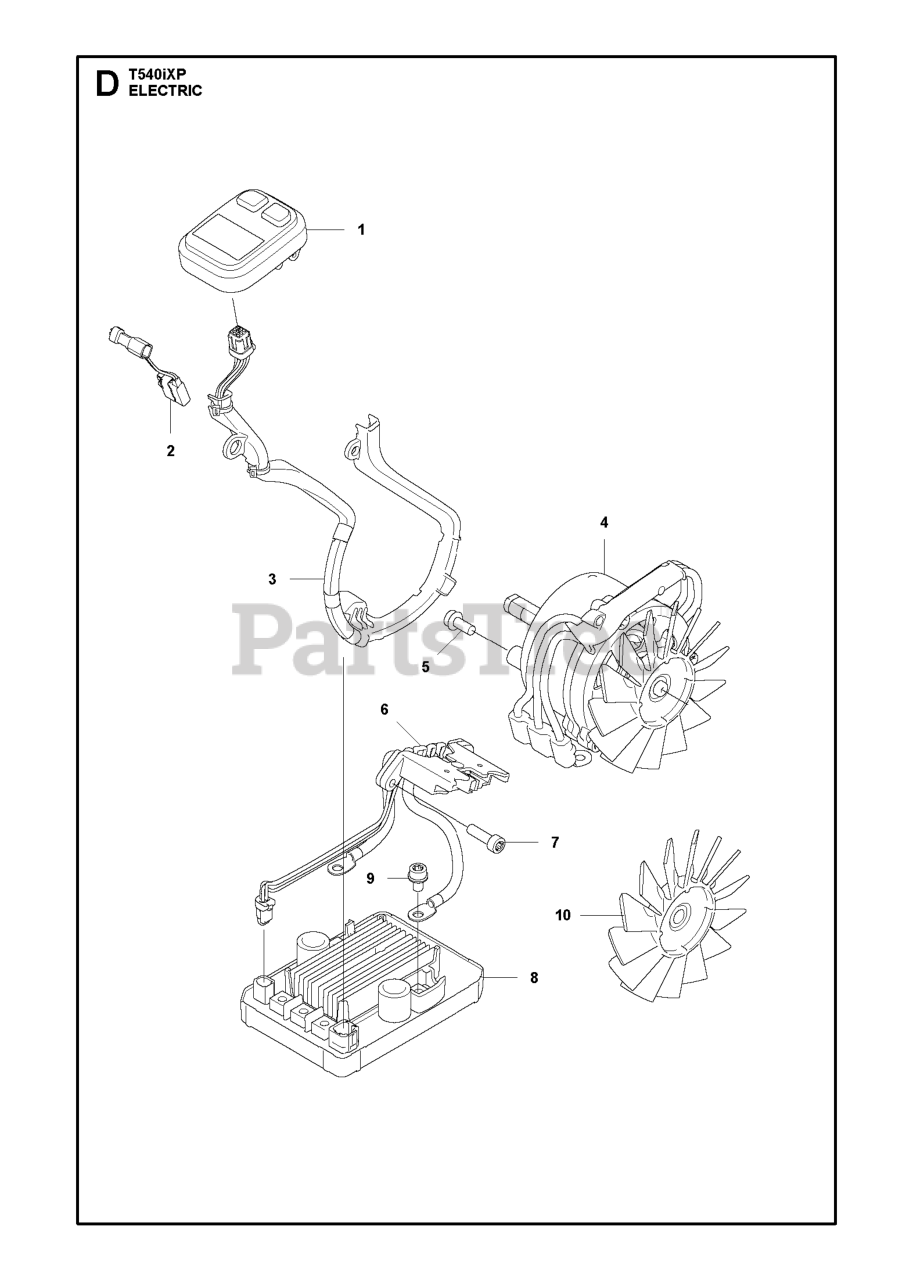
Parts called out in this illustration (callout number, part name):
1	Control Panels
3	Wiring Harness
5	SCREW
6	Wiring Harness
7	SCREW ITXSCT PW4.2X18 10.9 ZN
8	CONTROL UNIT
9	SCREW ITXSCFM M5X8 T27 10.9 Z
